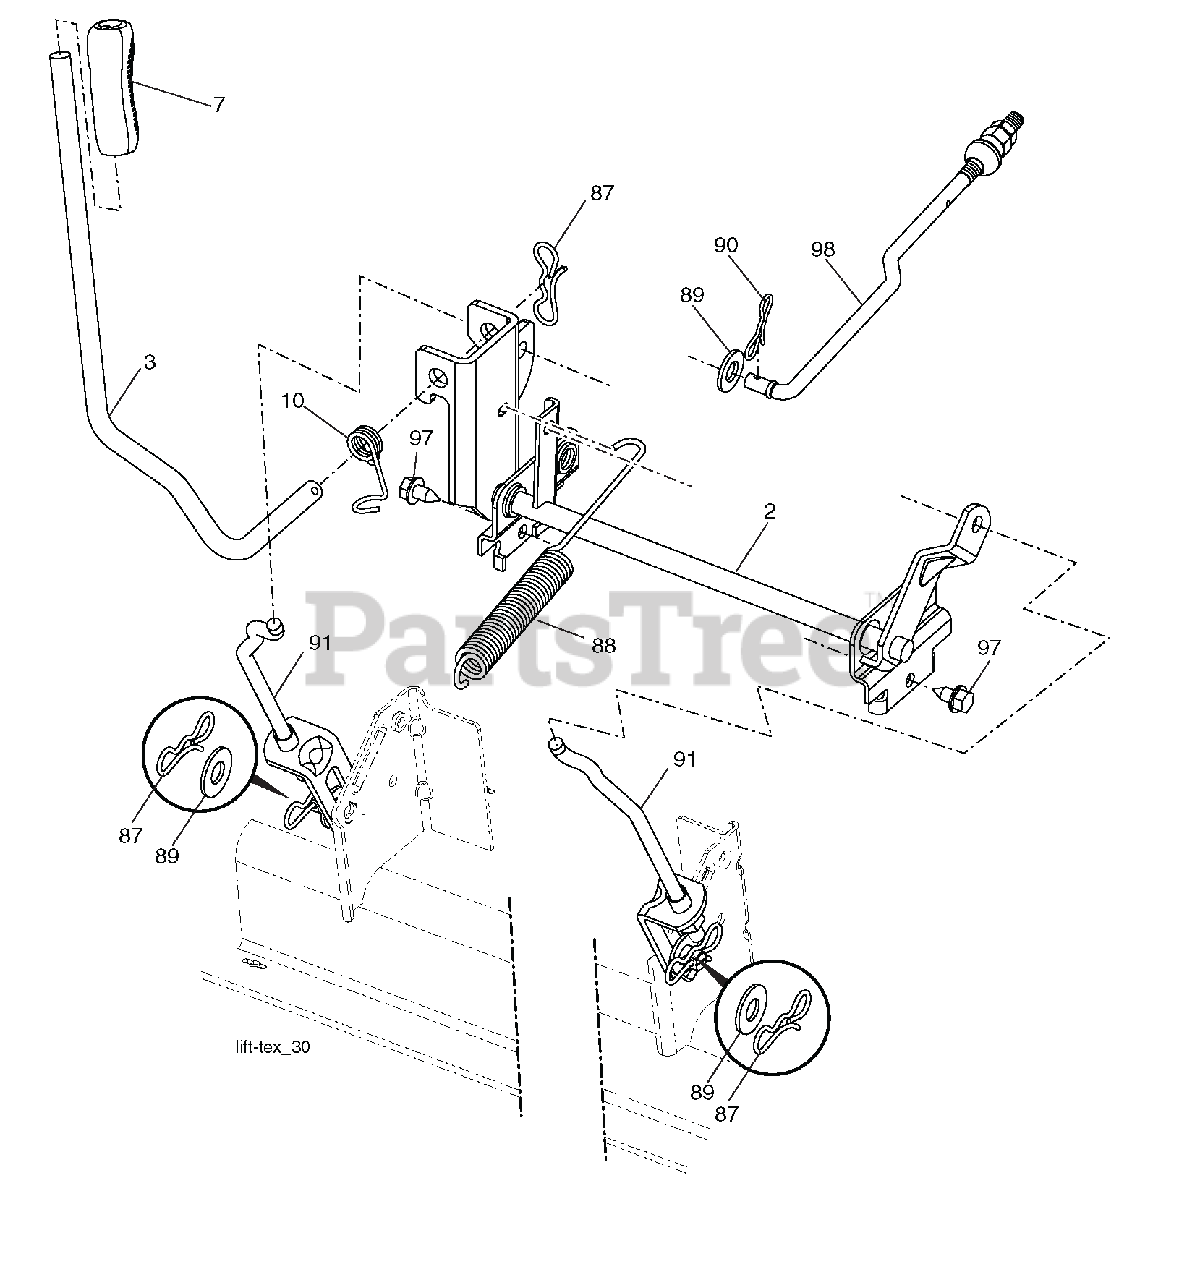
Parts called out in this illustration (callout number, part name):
2	SHAFT ASM., LIFT
3	LEVER.LIFT.HANDLE.LT
7	GRIP LEVER 5625 LD BLACK 428
10	SPRING.TORSION.HANDLE.LIFT
87	PIN.COTTER.7/16.BOW TIE LOCK
88	SPRING.LIFT ASSIST
89	WASHER.CLEAR ZINC
90	PIN.COTTER.5/16.BOW TIE LOCK
91	LINK.LIFT.SUSP.MOWER.REAR
97	SCREW.HEXWSH THDR3/8-16X3/4.BL
98	LINK.LIFT.SUSP.MOWER.FRONT
